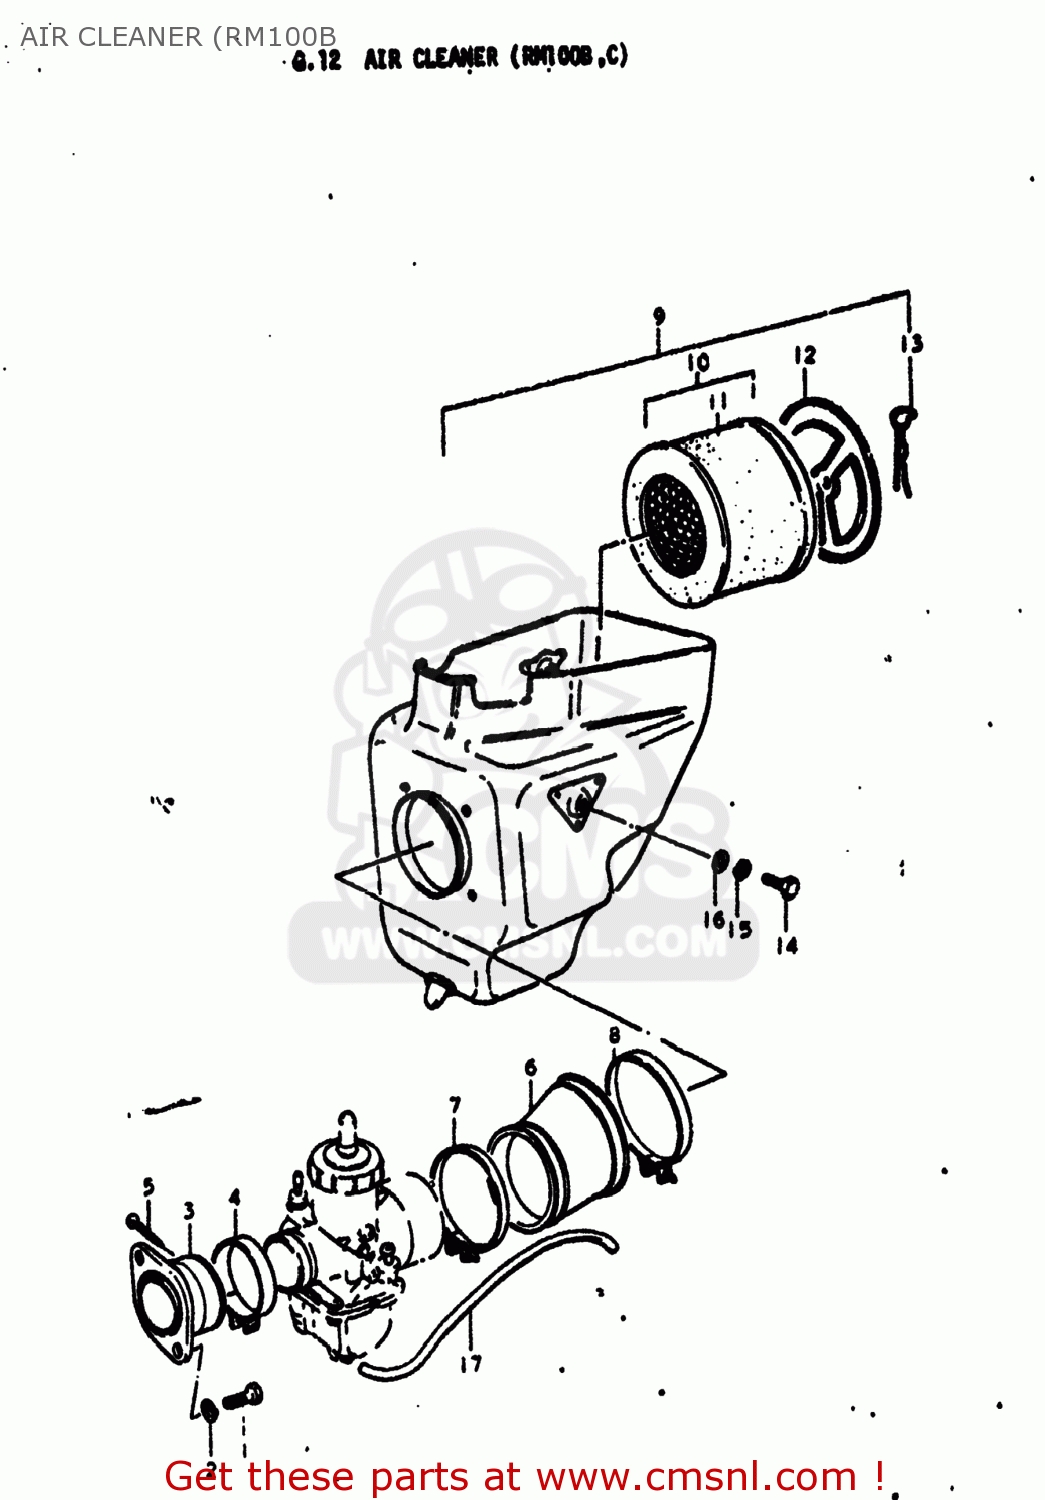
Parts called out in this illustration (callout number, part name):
1	BOLT
2	LOCK WASHER
3	PIPE,INTAKE
4	CLAMP
5	SCREW 5X20
6	HOSE,CARBURETOR AIR INLET
7	CLAMP
8	CLAMP
9	CLEANER ASSEMBLY,AIR
10	FILTER ASSY,AIR CLEANER
11	ELEMENT,AIR CLEANER
12	CAP
13	SPRING,AIR CLEANER
14	BOLT
15	LOCK WASHER
16	WASHER
17	HOSE
